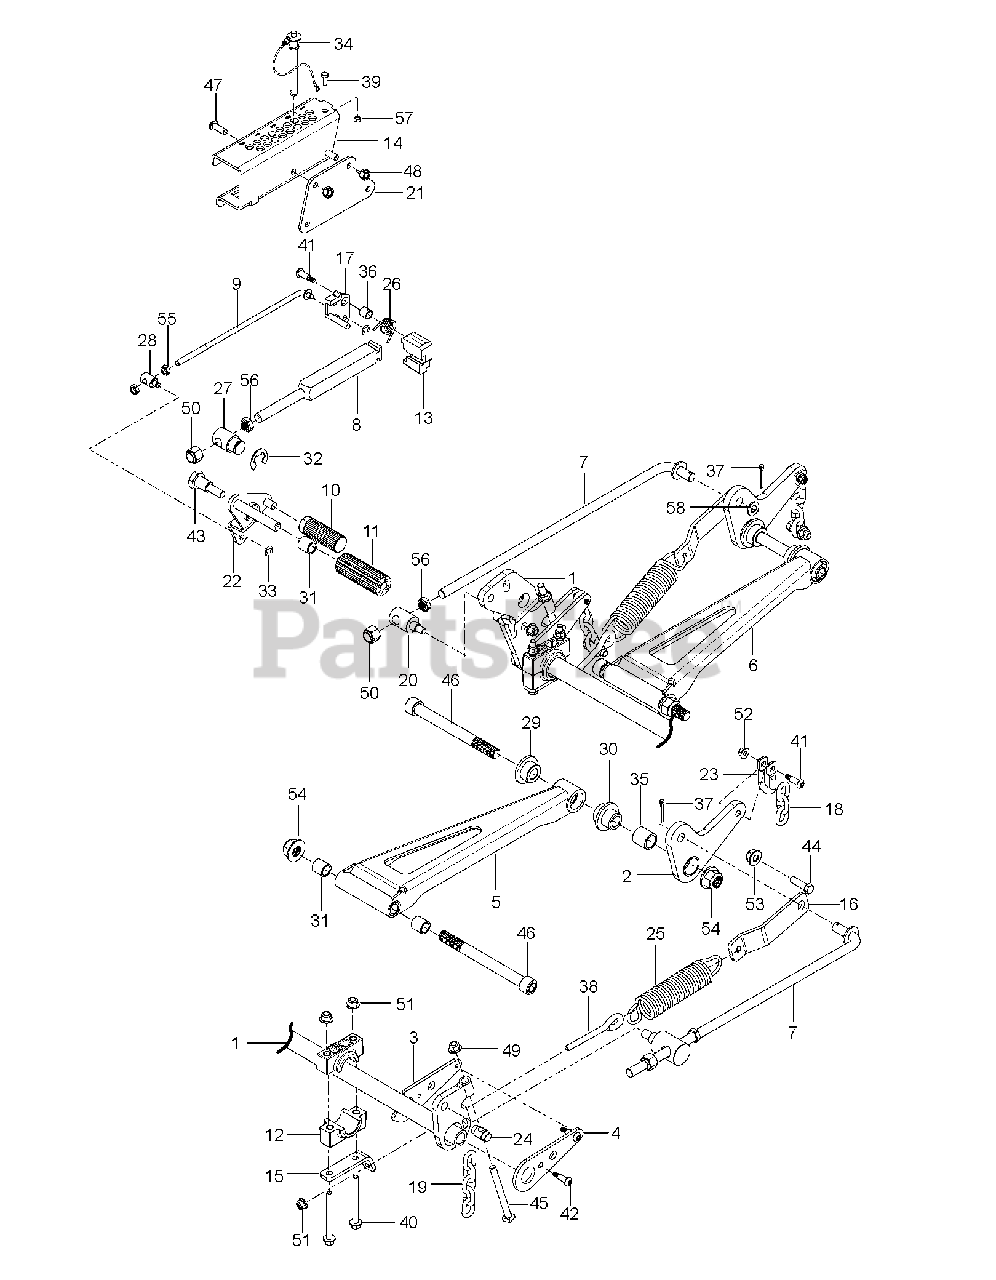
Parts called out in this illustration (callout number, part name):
1	SHAFT.WLDMNT.FRNT.DECK.LFT.PNT
2	ARM.PNT.BELL.CRANK.REAR
3	ARM.DECK.LIFT.INNER.BLACK
4	ARM.LIFT.DECK.OUTER.POWER.BLK
5	ARM.DRAWBAR.LH
6	ARM.DRAWBAR.RH
7	ROD. CONNECTING
8	ROD.HEIGHT.GAUGE
9	ROD.RELEASE.CONNECTING.TOE
10	PEDAL, DECK HEIGHT
11	PAD, FOOT PEDAL
12	BLOCK, PILLOW
13	BLOCK.ROD.END
14	BRACKET.ADJUSTMENT.HEIGHT.ORNG
15	BRACKET.PILLOW.BLOCK.PNT.BLACK
16	BRACKET.SPRING.ATTACH.PNT
17	LEVER.LOCK.TRANSPORT
18	LIFT CHAIN - 3 LINK
19	LIFT CHAIN
20	PIVOT.CONNECTING.ROD
21	PLATE.HEIGHT.GAUGE.MOUNT.PNT
22	LEVER ASSY TOE RELEASE
23	SHACKLE.CHAIN
24	SHAFT.TRUNNION.ATTACH
25	SPRING.LIFT.DECK.EXTNSN.PZ/PZT
26	SPRING.TORSION.RELEASE.LEVER
27	SWIVEL.HEIGHT.BAR
28	SWIVEL.TOP.RELEASE
29	BUSHING.DECK.INNER
30	BUSHING.DECK.OUTER
31	BUSHING, SLEEVE 3/4 X 1.0
32	E-RING 1"
33	E RING 3/8"
34	PIN.PUSH.BUTTON.DETENT..5X3.5
35	BEARING.FLANGED.1.25IDX.75
36	BEARING.SLEEV..375X.500X.750LG
37	COTTER PIN 1/8 X 2
38	EYE BOLT, 3/8 X 4"
40	SCREW.HHFS3/8-16X3.75.GR8
41	SCREW.SHOULDER.375X875.5/16-18
42	SCREW.SHLDR..375.5/16-18.88.LG
43	BOLT, SHOULDER
44	HCS 7/16-20 GD 8 SPEC
45	SCREW.HHC.7/16-14 X 4.50
46	SCREW.SOCKET.HEADCP.3/4-10X7.5
47	SCREW.BUTTON.HEAD.CAP.3/8-16X1
48	NUT 3/8C CENTERBLOCK
49	7/16-14 HEX NUT W/NYL RING ZD
50	NUT 5/8-11 NYLOC
51	NUT 3/8-16 HEX FLG NYLOC ZD
52	5/16-18 NYLOC FLANGE NUT
53	NUT 7/16-14 HEX WHIZ LK
54	NUT.HEX.FLANGED.3/4-10.NYLOK
55	NUT 3/8-24 JAM
56	NUT.HH.THIN.NYL.5/8-11 GR5
57	RP_NUT 1/4-20 NYLOC
